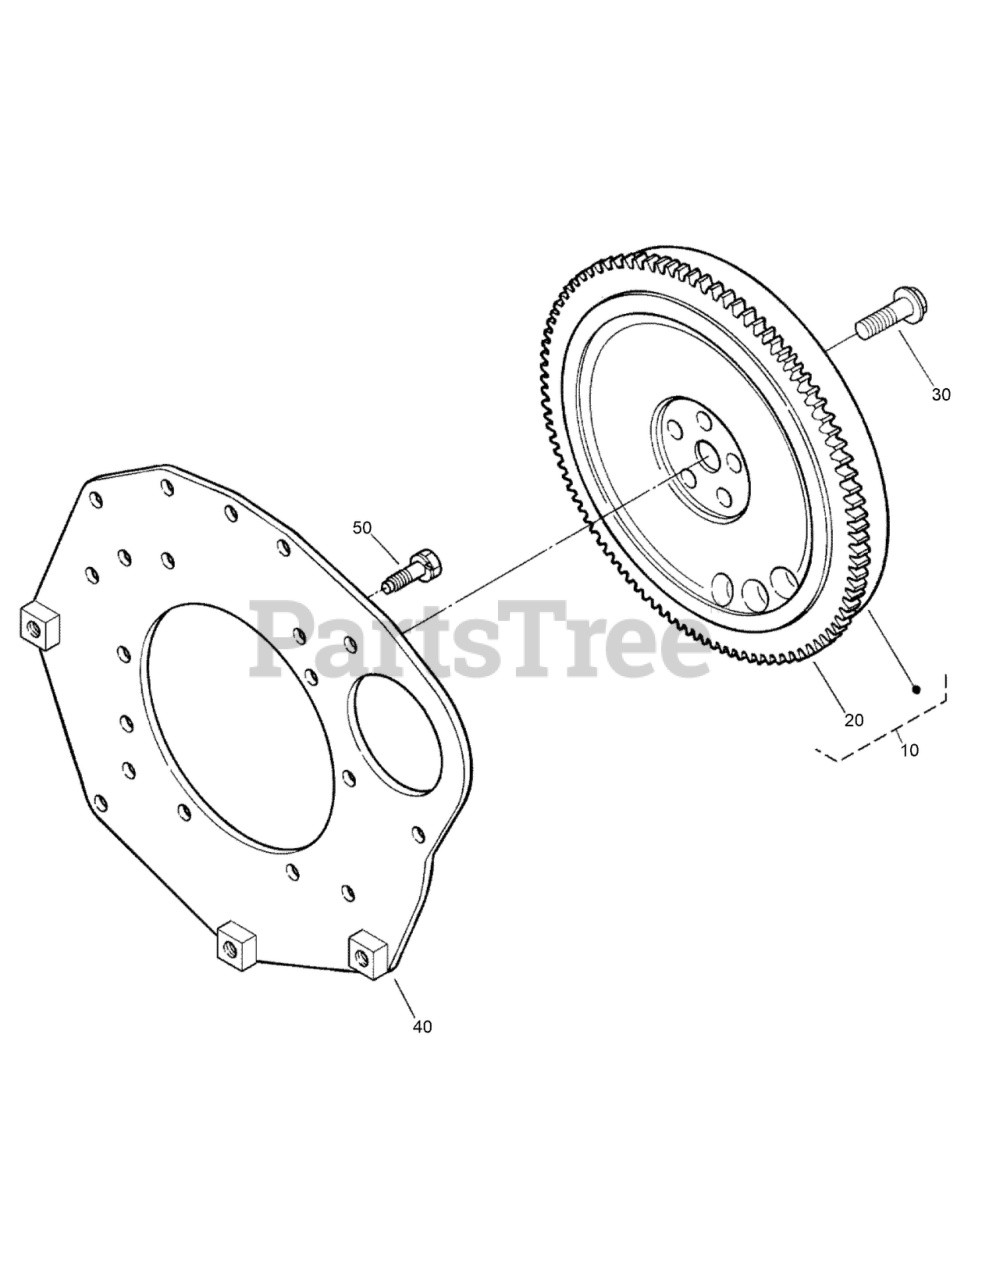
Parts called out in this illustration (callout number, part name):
10	FLYWHEEL ASM
20	RING-GEAR
30	BOLT-FLYWHEEL
50	BOLT,SEMS
